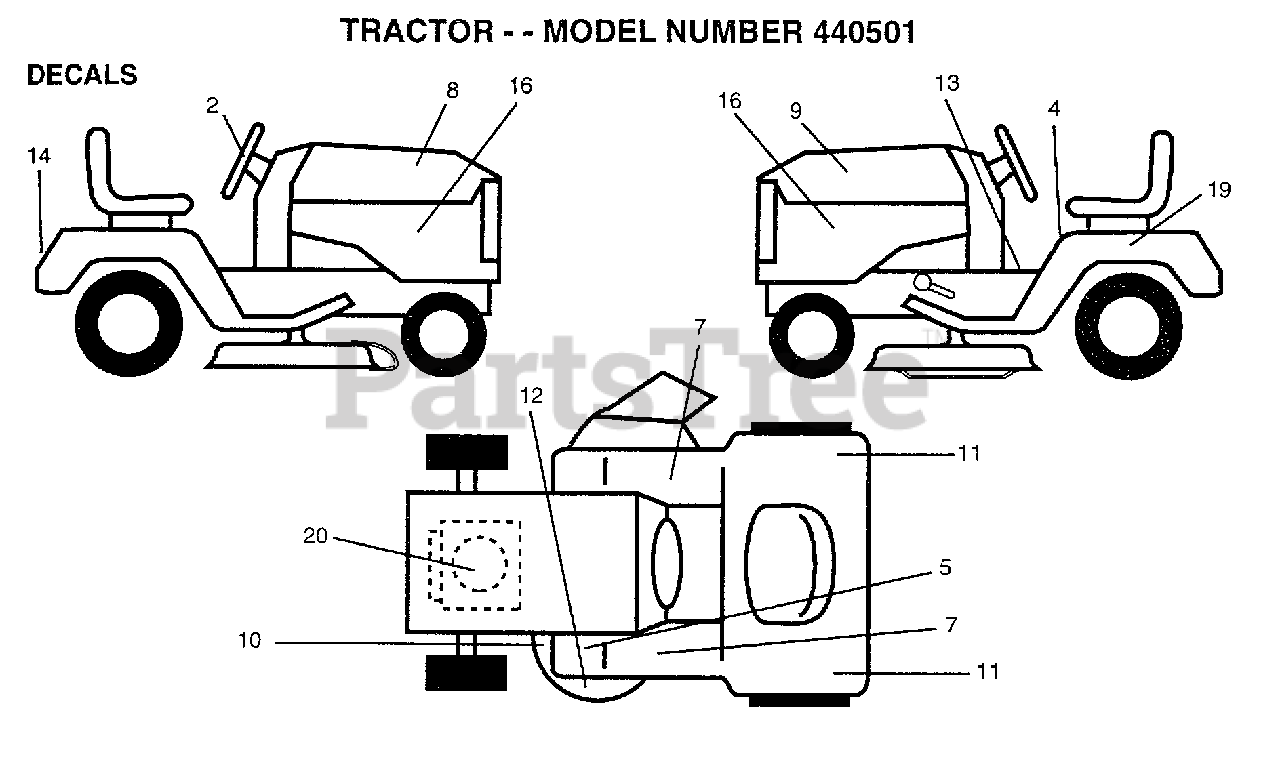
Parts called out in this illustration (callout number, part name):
2	DECAL.WHL.STRG.
4	DECAL
7	FOOTREST PAD
8	DECAL. HOOD RH
9	DECAL HOOD LH
10	DECAL
11	DECAL.FEND.QUICKS
12	DECAL.MOWER
14	DECAL.FENDER
16	DECAL.PHL SIDE
19	DECAL.BTRY.DANGER
20	DECAL, HP, ENGINE
